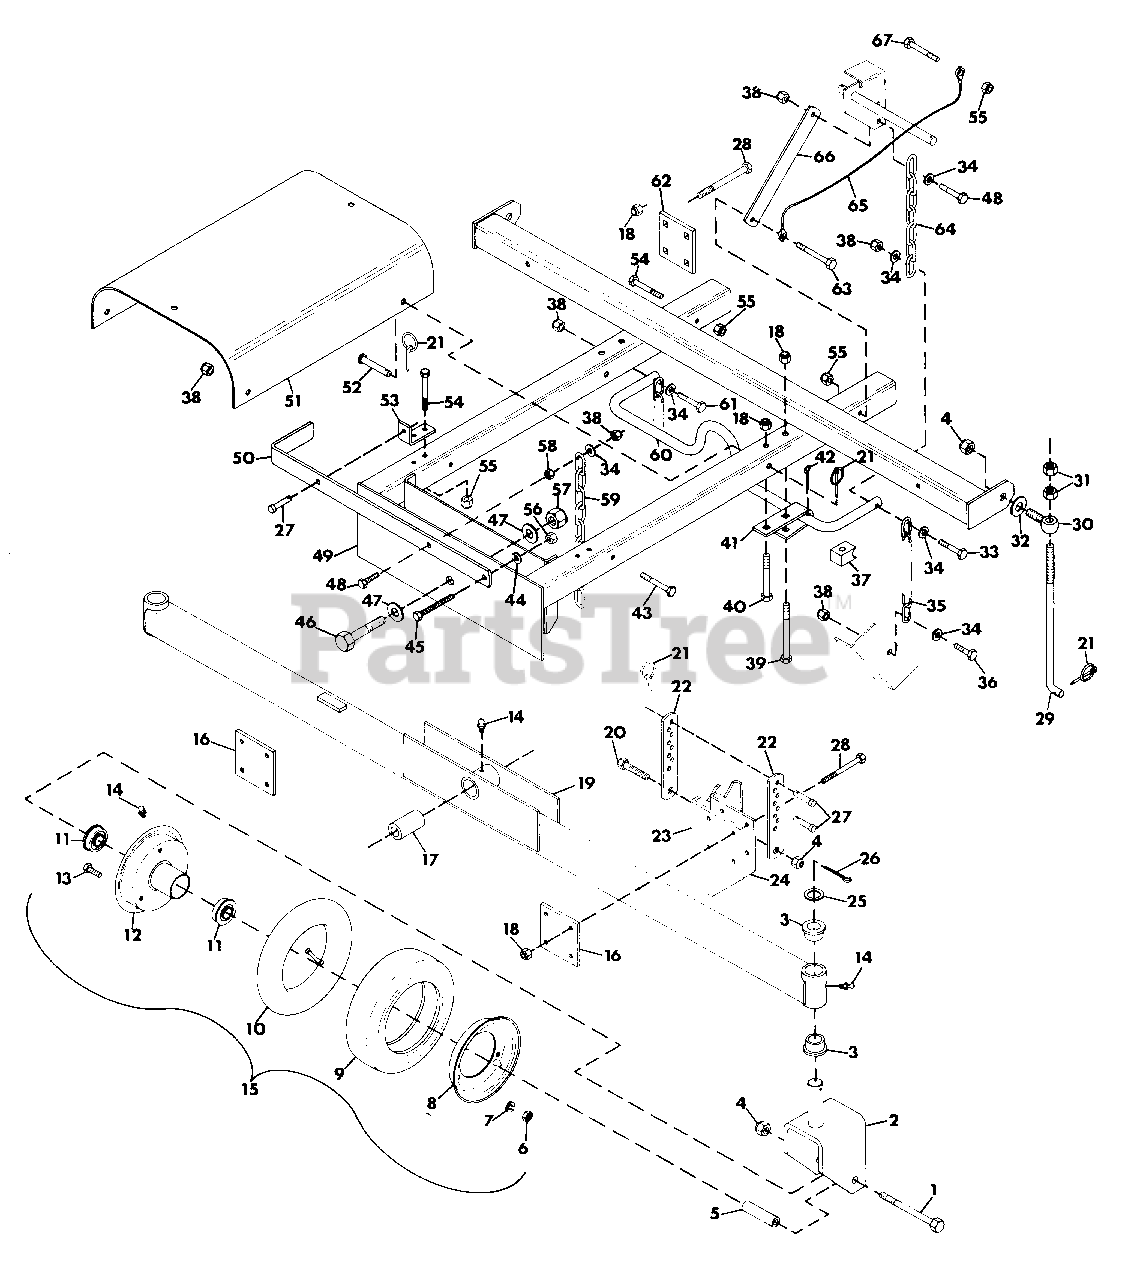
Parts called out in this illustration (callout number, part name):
1	BOLT, HEX 1/2-13X5.00
2	WELDMENT, CASTER FORK
3	BUSHING, PIVOT
4	NUT, LOCK 1/2-13
5	BUSHING, WHEEL .520X.750X3.312
6	NUT, HEX 3/8-24
7	WASHER, LOCK 3/8 SP HEAVY
8	WHEEL, HALF PLAIN
9	TIRE, GAUGE WHEEL
10	TUBE, INNER
11	BEARING, GAUGE WHEEL
12	WHEEL, HALF WITH TUBE
13	BOLT, HEX 3/8-24X.75
14	FITTING, LUBE 1/4-28
15	WHEEL, GAUGE
16	PLATE, ADJUSTMENT CLAMP
17	TUBE, PIVOT
18	NUT, LOCK 3/8-16
19	WELDMENT, AXLE
20	BOLT, HEX 1/2-13X2.00
21	KLIK PIN
22	STRAP, ADJUSTMENT
23	PLATE, HEIGHT ADJUSTMENT-L.H.
23	PLATE, HEIGHT ADJUSTMENT-R.H.
24	PLATE, HEIGHT ADJUSTMENT-L.H.
24	PLATE, HEIGHT ADJUSTMENT-R.H.
25	RACE, BEARING THRUST
26	PIN, COTTER 3/16X1.62
27	PIN, CLEVIS
28	BOLT, HEX 3/8-16X3.25
29	ROD, HEIGHT ADJUSTMENT
30	BOLT, EYE
31	NUT, JAM 1/2-13 HEX
32	WASHER, FLAT .500X1.250X.083
33	BOLT, HEX 5/16-18X1.75
34	WASHER, FLAT .406X.812X.065
35	CHAIN, LIFT
36	BOLT, HEX 5/16-18X1.00
37	STOP, NYLON
38	NUT, LOCK 5/16-18
39	BOLT, HEX 3/8-16X4.00
40	BOLT, HEX 3/8-16X3.00
41	BRACKET, AXLE SUPPORT
42	PIN, COTTER 1/8X1.25
43	BOLT, HEX 5/16-18X2.50
44	WASHER, LOCK 3/8
45	BOLT, 3/8-16X3 SPECIAL
46	BOLT, HEX 3/4-10X4.50
47	WASHER, FLAT .812X.469X.130
48	BOLT, HEX 5/16-18X1.25
49	WELDMENT, MOWER FRAME
50	BAR, LIFT
51	GUARD, PTO SHAFT
52	PIN, CLEVIS 3/8X2.62
53	BRACKET, LIFT PIVOT
54	BOLT, 5/16-24X2.75
55	NUT, LOCK 5/16-24
56	NUT, JAM 3/8-16
57	NUT, LOCK 3/4-10
58	NUT, JAM 5/16-18
59	CHAIN, HEIGHT ADJ.
60	ARM, PIVOT
61	BOLT, HEX 5/16-18X1.50
62	PLATE, ATTACHMENT CLAMP
63	BOLT, 5/16-24X3.5
64	CHAIN, LIFT
65	CABLE, STOP
66	BAR, DECK LIFT
67	BOLT, 5/16-24X2.25
NS	DECAL, PRO MASTER-50
